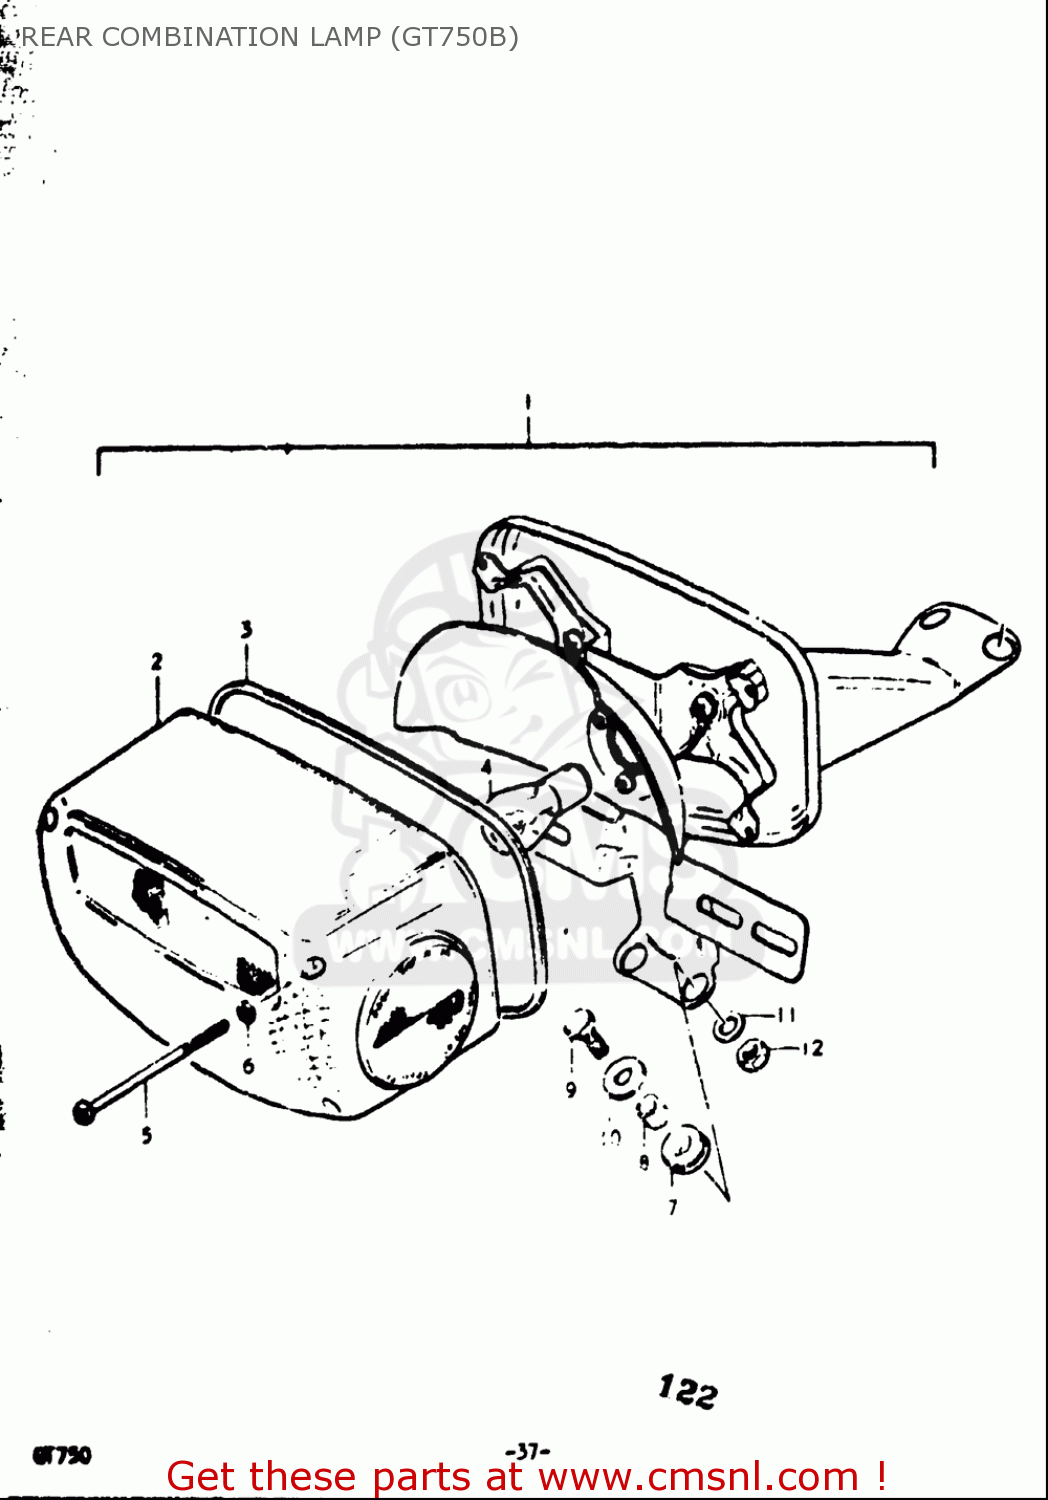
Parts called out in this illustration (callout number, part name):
2	LENS
3	GASKET (NAS)
4	BULB(12V23W)
6	GASKET (NAS)
7	CUSHION
8	SPACER
9	BOLT
10	WASHER(6.5X20X1.2)
11	WASHER
12	NUT
